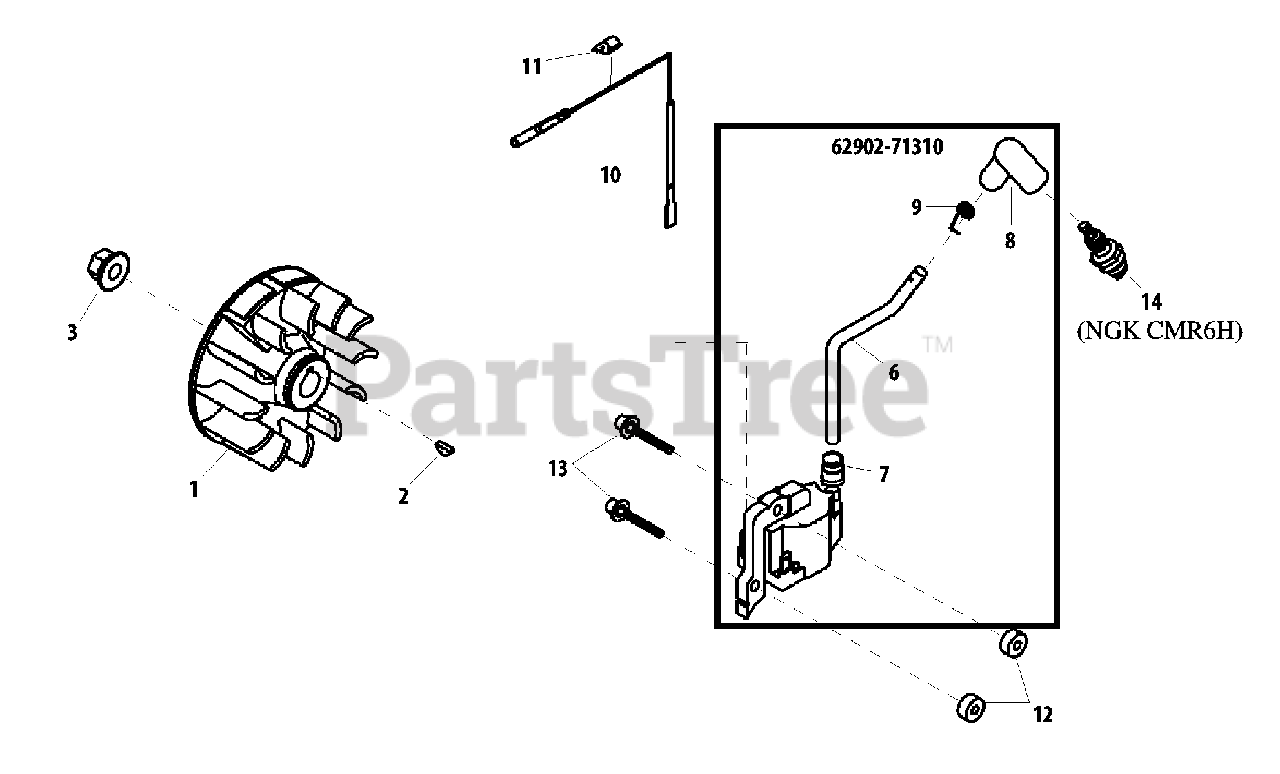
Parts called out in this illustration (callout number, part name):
1	FLYWHEEL
2	KEY - 3X10
3	NUT - 8
7	GROMMET
8	CAP, SPARK PLUG
9	TERMINAL, SPARK PLUG CAP
10	LEAD - IGNITION
11	GROMMET
12	INSULATOR
13	SCREW - 4X26
14	SPARK PLUG -- CMR-6H
62902-71310	IGNITION COIL ASSY
